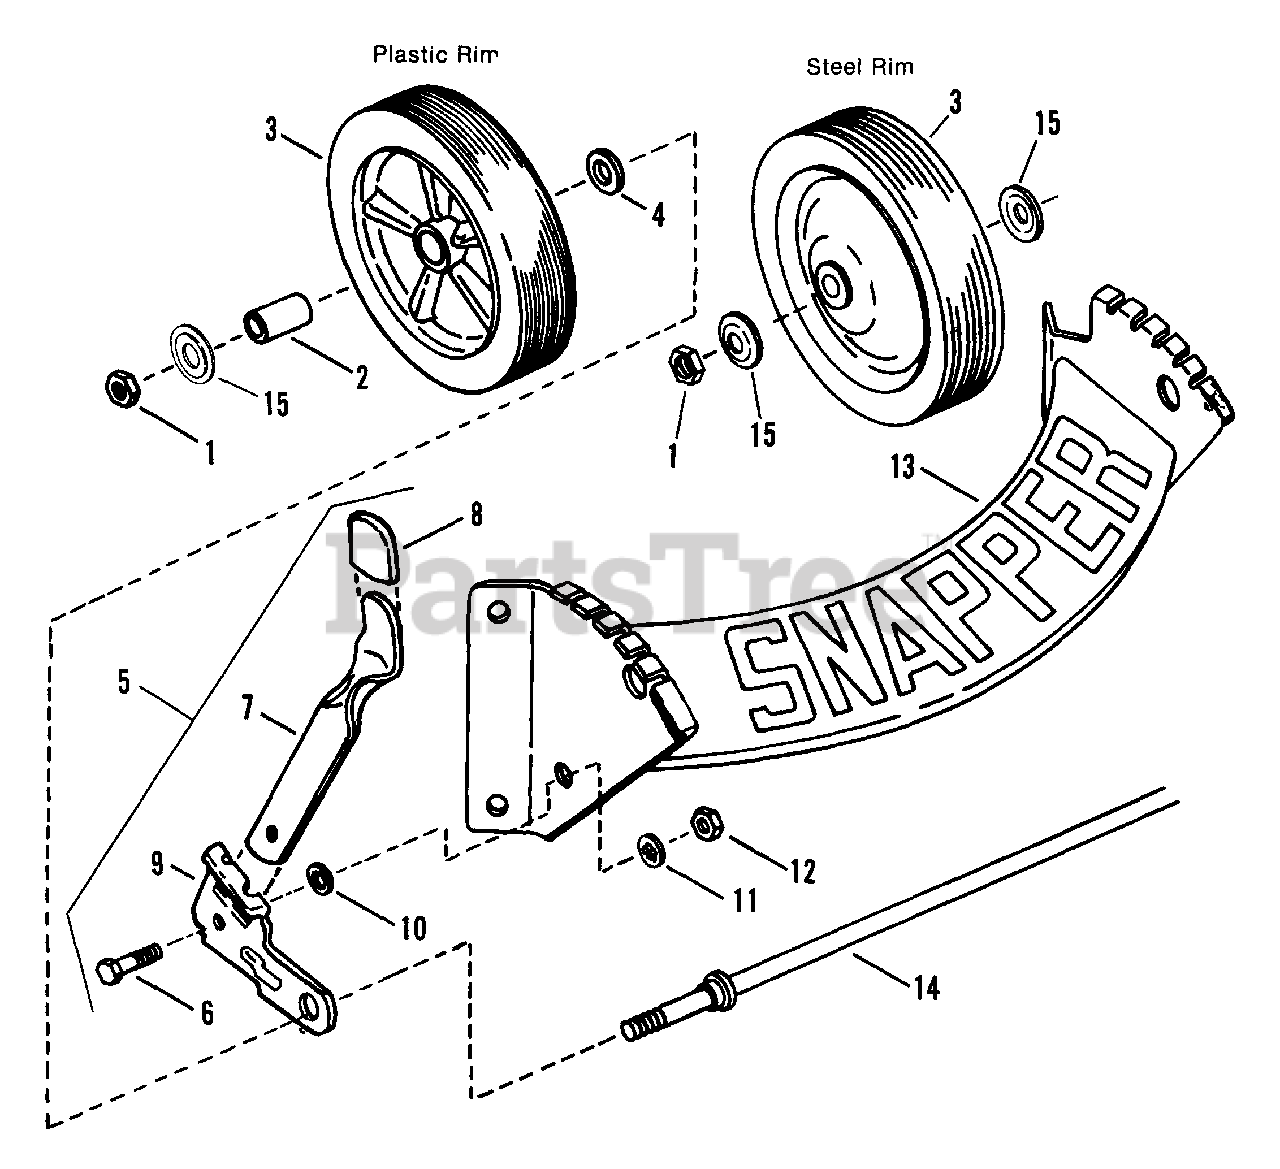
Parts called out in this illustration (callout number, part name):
1	NUT, 7/16-20 Hex Centerlock
2	BUSHING, Axle
3	WHEEL, Front, (7 x 1.50 Plastic Rim)(B & S)
4	WASHER, Steel
5A	ARM ASSEMBLY, Left Wheel
5B	ARM ASSEMBLY, Right Wheel
6	BOLT, 5/16-18 Shoulder
7	LATCH, Height
8	GRIP
9A	ARM, Left Wheel
9B	ARM, Right Wheel
10	RETAINER, 5/16 Bolt
11	WASHER, 5/16 Int. Toothlock
12	NUT, 5/16-18 Hex
13	BRACKET, Front Wheel
14	AXLE
15	HUB-CAP (2 per wheel)
